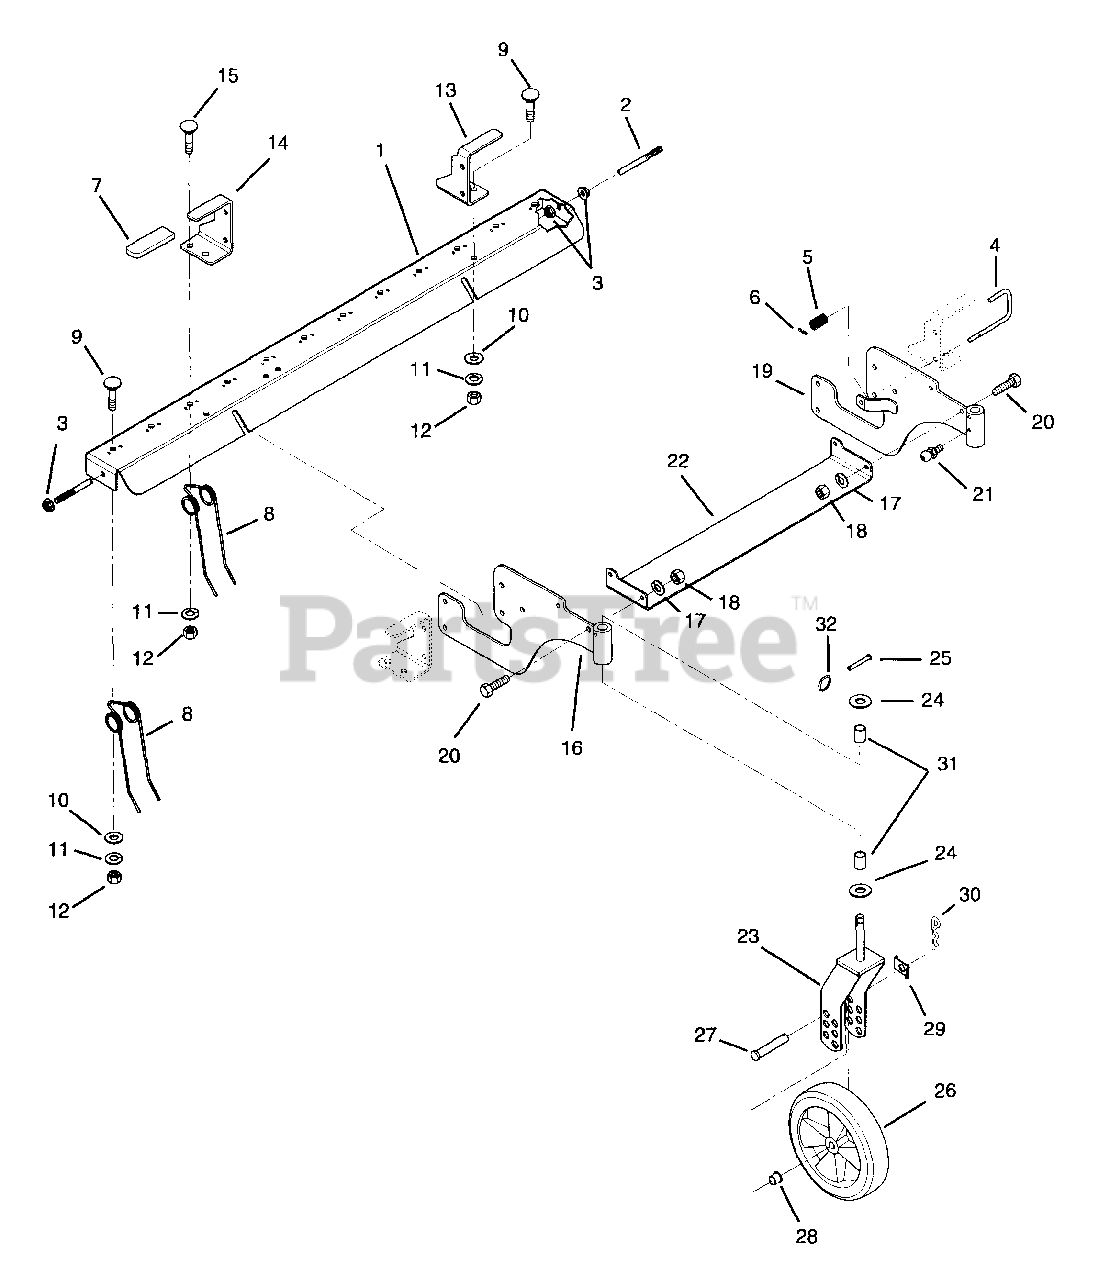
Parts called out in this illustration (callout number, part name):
1	CHANNEL
2	ROD
3	@NUT-SPNLK-FLG .25-20 YWZC
4	J-PIN .312 DIA. YWZC
5	SG-COMP .063X.53X1.187
6	PIN-ROLL .094X.750
8	SPRING
9	BLT-RDHDSQSHK.31-18X.75 GR2 YW
10	WSHR-FL-STL .328X1.0X.094 PL
11	WSHR-LK .312X.097 HVY YWZC
12	@NUT-HEX .31-18 YWZC
13	BRACKET-CHANNEL PIVOT LH
14	BRACKET-CHANNEL PIVOT RH
15	BLT-RDHDSQNK .31-18X1.0 SHTYZ
16	SUPPORT-CHANNEL RH
17	WSHR-LK .250X.077 HVY YWZC
18	@NUT-HEX .25-20 YWZC
19	SUPPORT-CHANNEL LH
20	@BLT-HEX .25-20X.75 GR5 YWZC
21	FTG-LUBE .25-28X.256 YWZC
23	WHEEL YOKE WELDMENT
24	WSHR-FL-STL .630X1.250X.062 YZ
25	PIN-CLEV .25X1.75
26	WHEEL
27	PIN-CLEV .494X2.62 YWZC
28	BSHG-FLG .500X.625X.500X.750
29	AXLE TAB
30	PIN-HAIR-INT .15X.43X2.75 YWZC
31	BSHG-SLV .625X.750X.500 BR
32	KICKOUT RING YWZC
